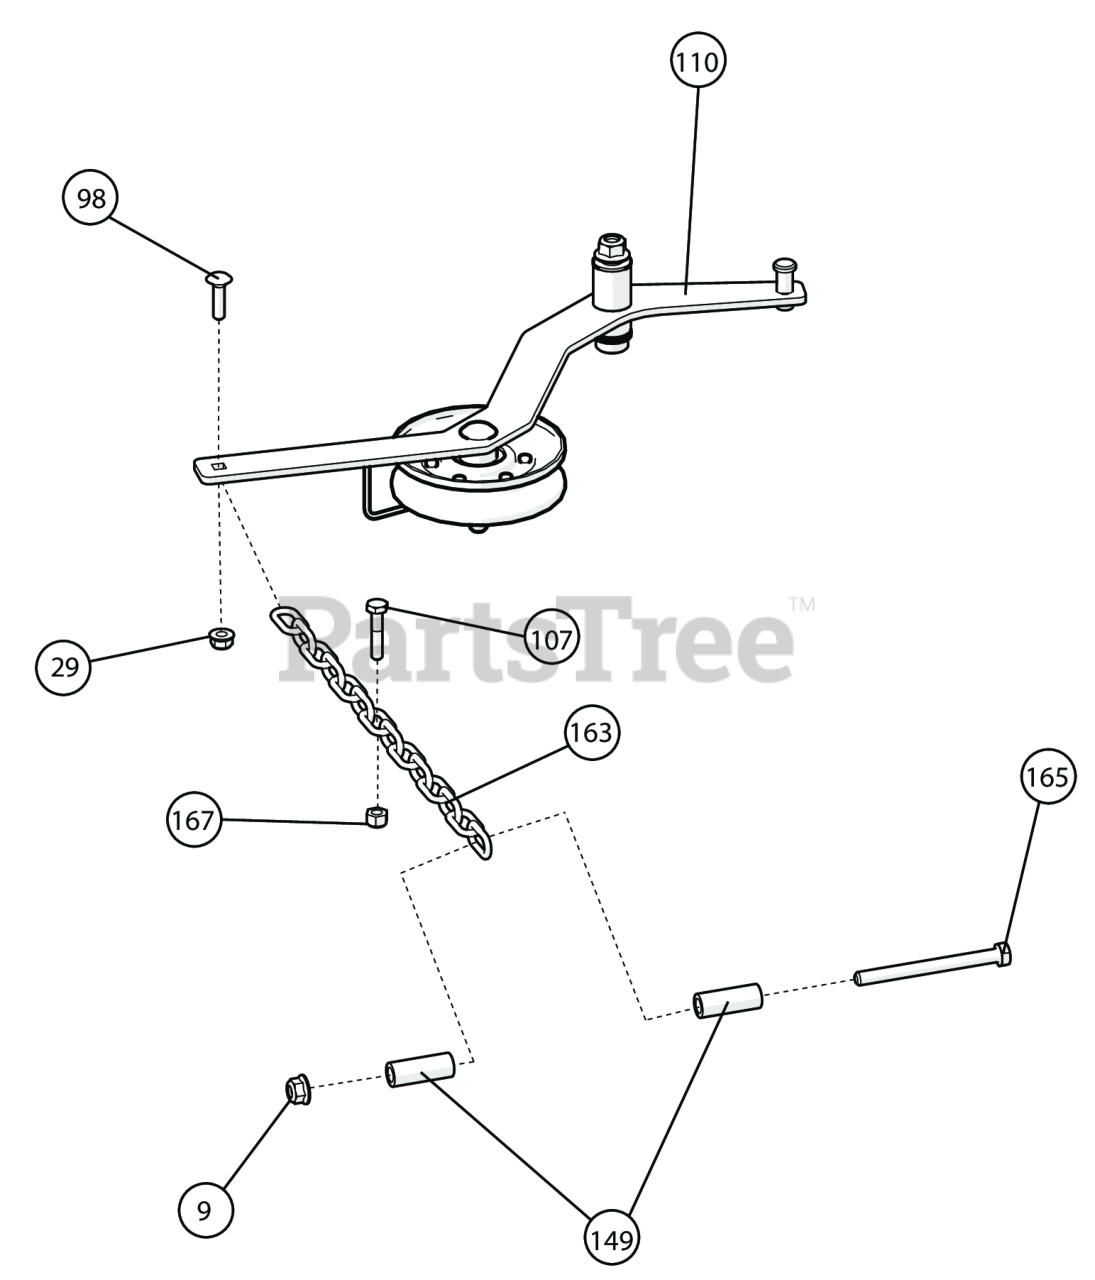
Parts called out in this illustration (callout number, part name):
9	NUT-HEX-NYLK, FLG .3125-18 ZP
29	NUT-HEX-NYLK, FLG .250"-20 ZP
98	BOLT CARRIAGE 1/4"-20 X 1" ZP
107	SCR-CAP, HEX .250"-20 X 1.250" 18-8 SS
110	WA, IDLER
149	SPACER - TINE SPROCKET
163	CHAIN, GRADE 30, 13" OAL
165	SCREWCAP 5/16"-18X3 1/2" HCS ZP
167	NUT LOCK 1/4"-20 HEX Z/P
